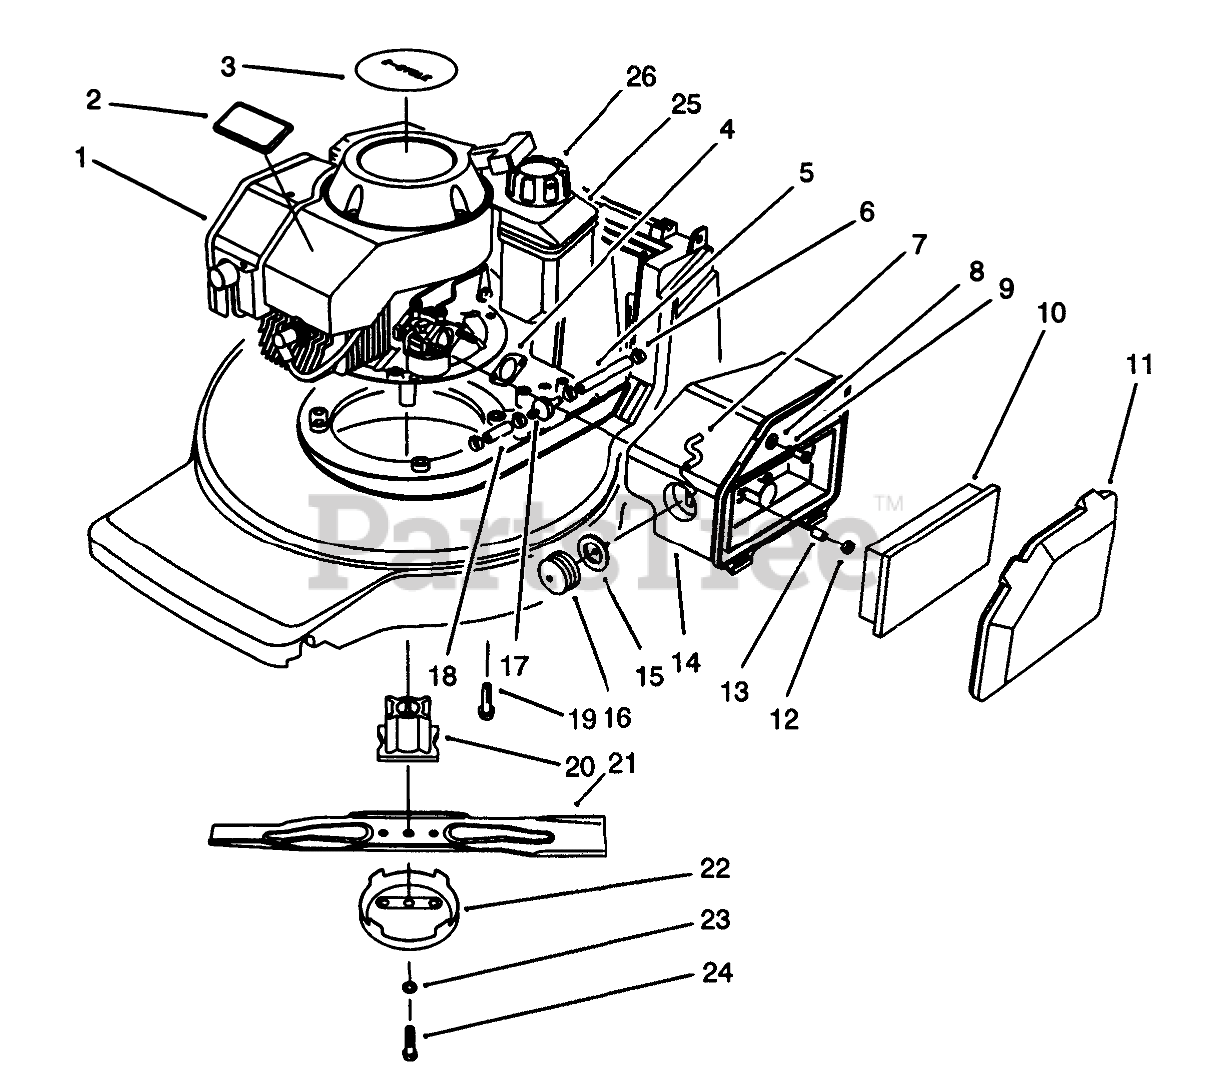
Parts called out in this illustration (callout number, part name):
1	ENGINE 121CC INT'L 2CYC
2	TORO LOGO PLT
3	DECAL- 2 CYC RECOIL
4	GASKET-AIR CLEANER
5	HOSE-FUEL
6	CLAMP-FUEL LINE
7	HOSE-PRIMER
8	WASHER-FLAT
9	SCREW-HH
10	ELEMENT-AIR CLEANER
11	COVER-AIR CLEANER
13	SPACER
14	BODY-AIR CLEANER
15	BODY-PRIMER
16	BULB-PRIMER
17	FILTER-FUEL
18	HOSE-FUEL
19	SCREW-HHF
20	BLADE RETAINER - 25 MM
21	Blade-48cm
22	CUP-SCALP, ANTI
23	WASHER-LOCK
24	BOLT-BLADE
25	FUEL TANK ASM
26	GAS CAP ASM
